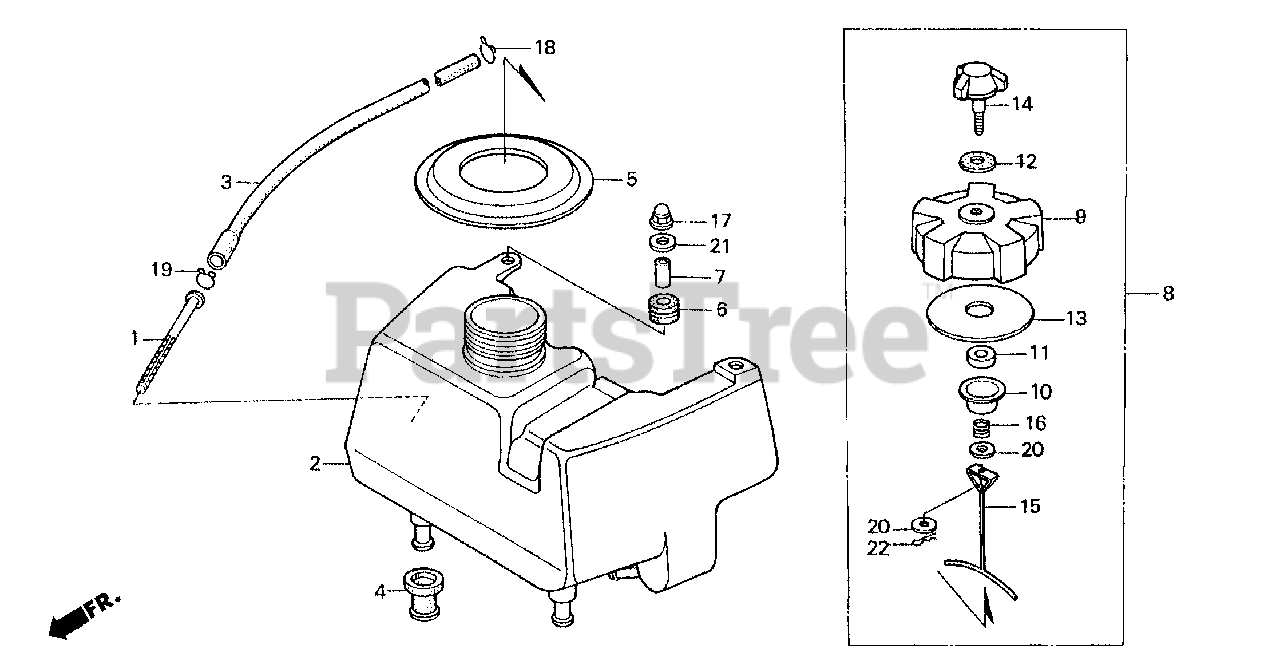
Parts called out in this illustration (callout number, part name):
1	FILTER, FUEL
2	TANK, FUEL
3	TUBE, FUEL
4	RUBBER C, TANK MOUNTING
5	RUBBER A, TANK MOUNTING
6	RUBBER B, TANK MOUNTING
7	COLLAR, TANK MOUNTING
8	CAP ASSY., FUEL TANK
9	BODY, FUEL CAP
10	INNER, FUEL CAP
11	SPONGE, FUEL CAP BREATHER
12	GASKET, VALVE
13	GASKET, FUEL CAP
14	VALVE, BREATHER
15	LINK, FUEL CAP
16	SPRING, FUEL CAP
17	NUT, CAP (6MM)
18	CLIP, TUBE (B10)
19	CLIP, TUBE (C12)
20	WASHER, FLAT (4MM)
21	WASHER, PLAIN (6MM)
22	PIN, LOCK (4MM)
